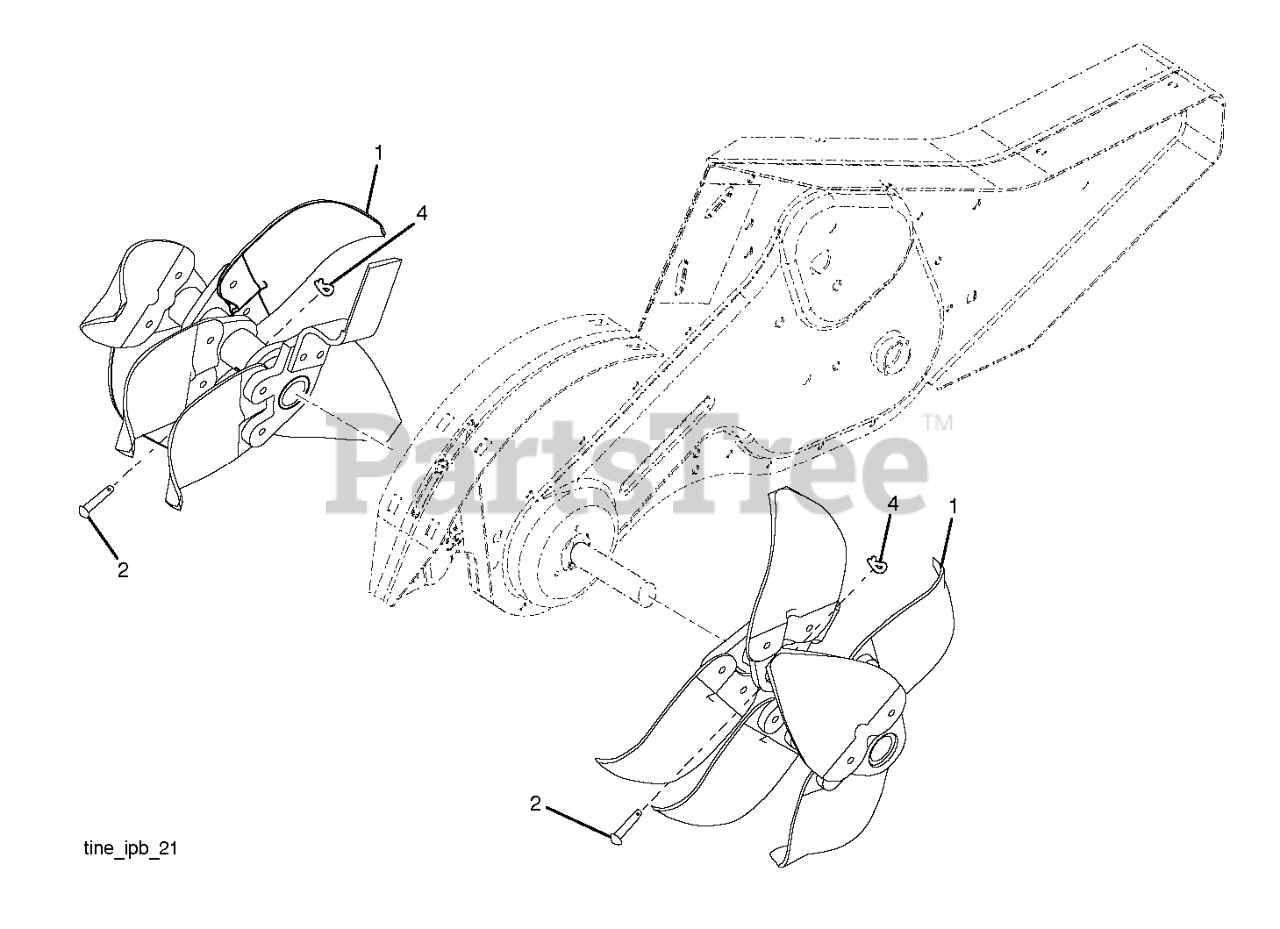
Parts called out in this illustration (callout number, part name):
1	TINE.ASM.DRT TILLER.479
2	PIN RETAINING SCREW
4	SPRING RETAINER
